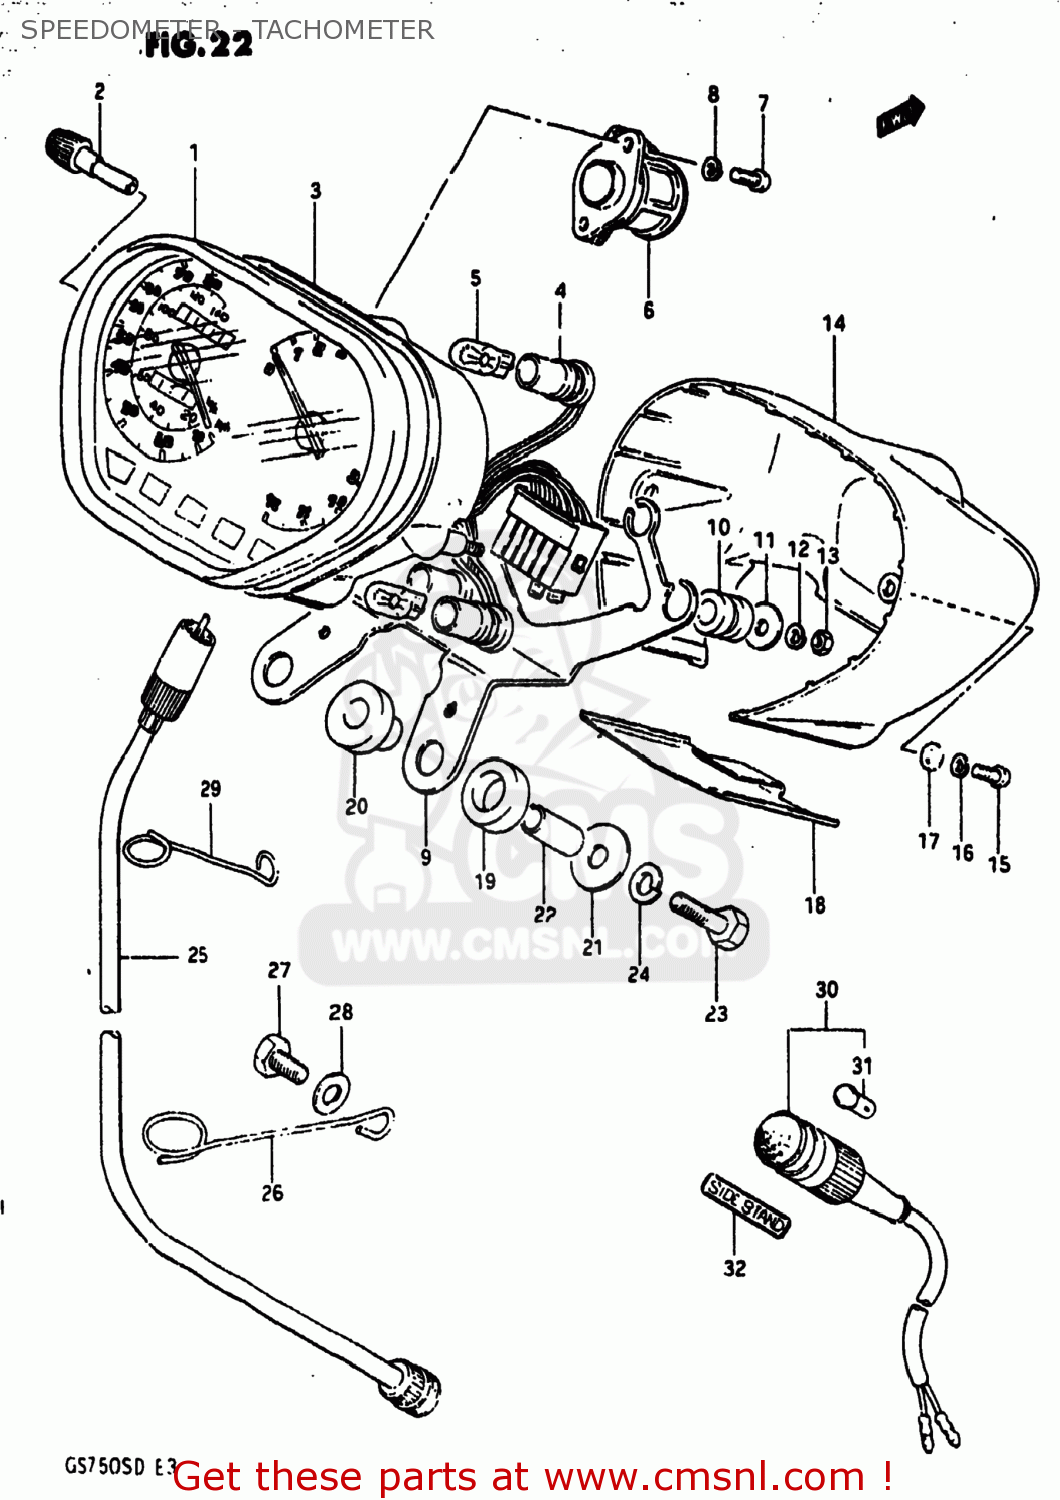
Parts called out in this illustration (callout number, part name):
1	SPEEDOMETER ASSEMBLY
2	KNOB,TRIP METER
3	CUSHION
4	SOCKET
5	BULB(12V3.4W,T10,BF175-01450A)
6	GEAR BOX,SPEEDOMETER
7	SCREW 4X10
8	LOCK WASHER
9	BRACKET,METER
10	CUSHION
11	WASHER,COMBINATION METER
12	LOCK WASHER
13	NUT
14	COVER,LWR
15	SCREW
16	LOCK WASHER
17	WASHER
18	PLATE,SPEEDOMETER
19	CUSHION
20	CUSHION
21	WASHER (6.5X24X1.6)
22	SPACER (6.1X8X15.5)
23	BOLT
24	LOCK WASHER
25	CABLE ASSEMBLY,SPEEDOMETER
26	CLAMP,SPEEDOMETER CABLE
27	BOLT, UPPER
28	WASHER
29	GUIDE,SPEEDOMETER CABLE UPR
30	LAMP ASSY,SPEED WARNING
31	BULB(12V3.4W,STANLEY,A72A)
